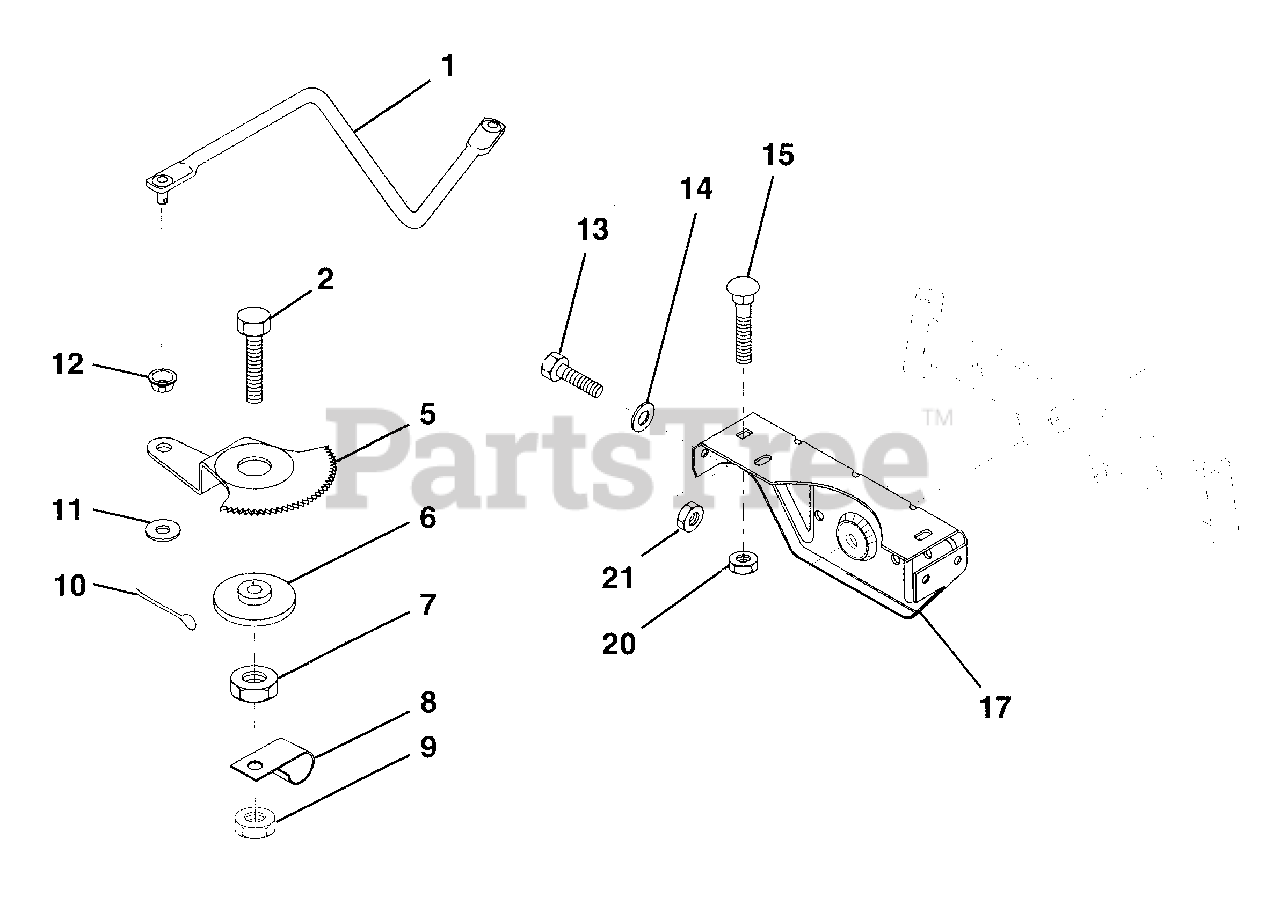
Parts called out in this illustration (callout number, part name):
1	Link, Drag
2	Bolt, Hex Head, Fin. 1/2-13 x 1-3/4
5	Gear, Sector
7	Nut, Heavy Hex, Top Lock 1/2-13 UNC
8	Clip, Insulated
9	Nut, Hex, Crownlock 3/8-16
10	Pin, Cotter 1/8 x 3/4
11	Washer 13/32 x 13/16 x 16 Gauge
13	Bolt, Hex Head 5/16-18 UNC x 3/4
14	Washer 11/32 x 7/8 x 16 Gauge
15	Bolt, Carriage 3/8-16 UNC x 3/4
17	Support, Front Axle
20	Nut, Hex, Crownlock 3/8-16 UNC
21	Nut, Hex, Crownlock 5/16-18
